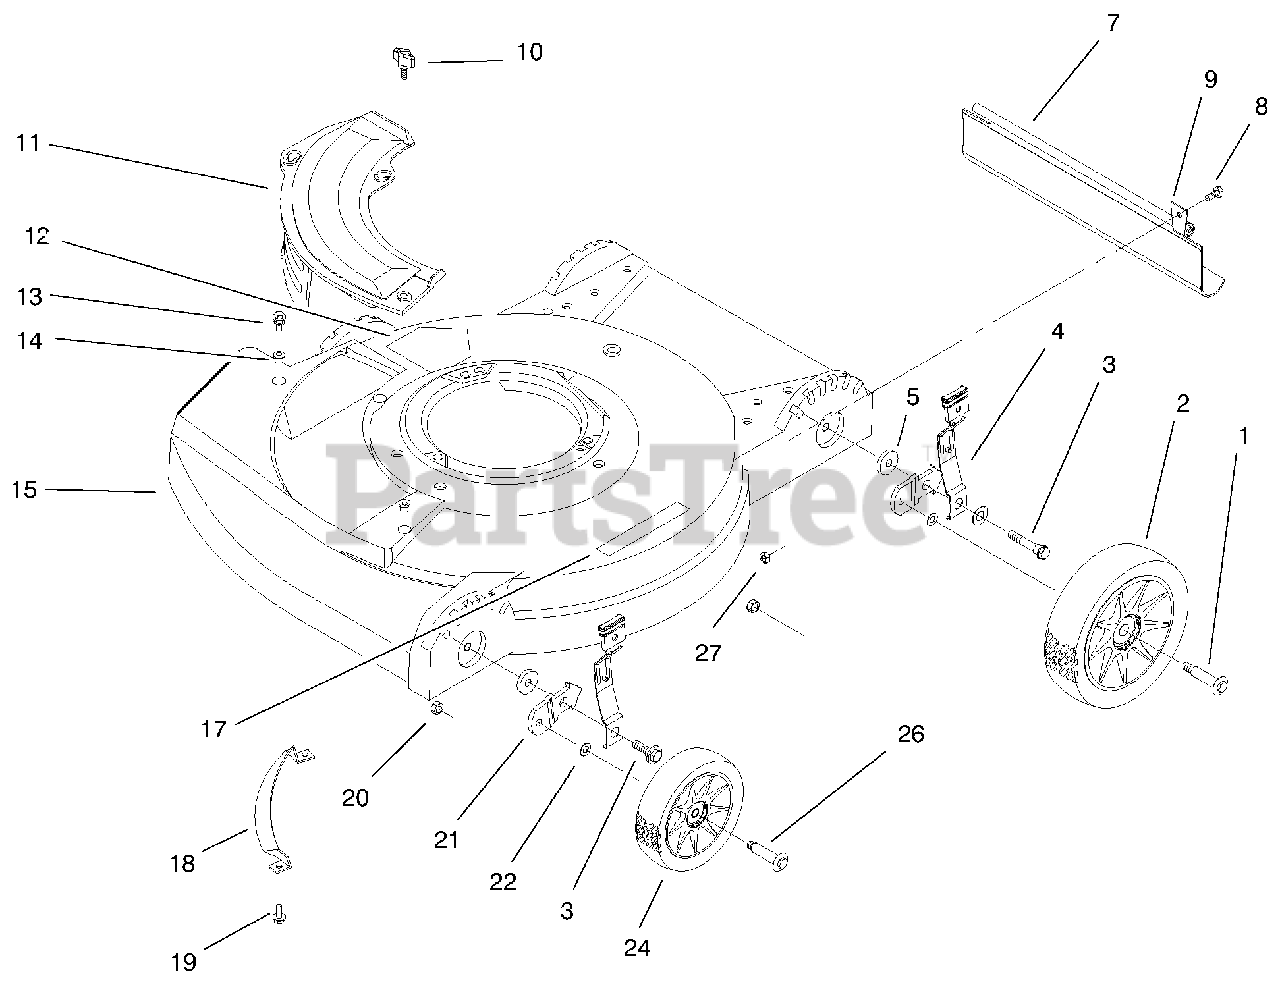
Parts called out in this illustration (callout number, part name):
1	Bolt-Shoulder
2	ASM-Wheel
3	Bolt-Ajustment
4	Knob & Spring
7	Shield-Trailing
8	Screw-HH
9	Clamp-Rod
10	Knob-Cover Plate
11	Mulch Plate-21"
12	Decal-Danger
13	Screw-Sems
14	Grommet-Plastic
15	Housing-21" Hp
17	Decal-Warning
18	Toe Bar 21
19	Screw-HWH
20	Nut-Lock
21	Bracket-Height
24	ASM-Wheel & Tire 6"
26	Bolt-Shoulder
27	Nut-Lock
